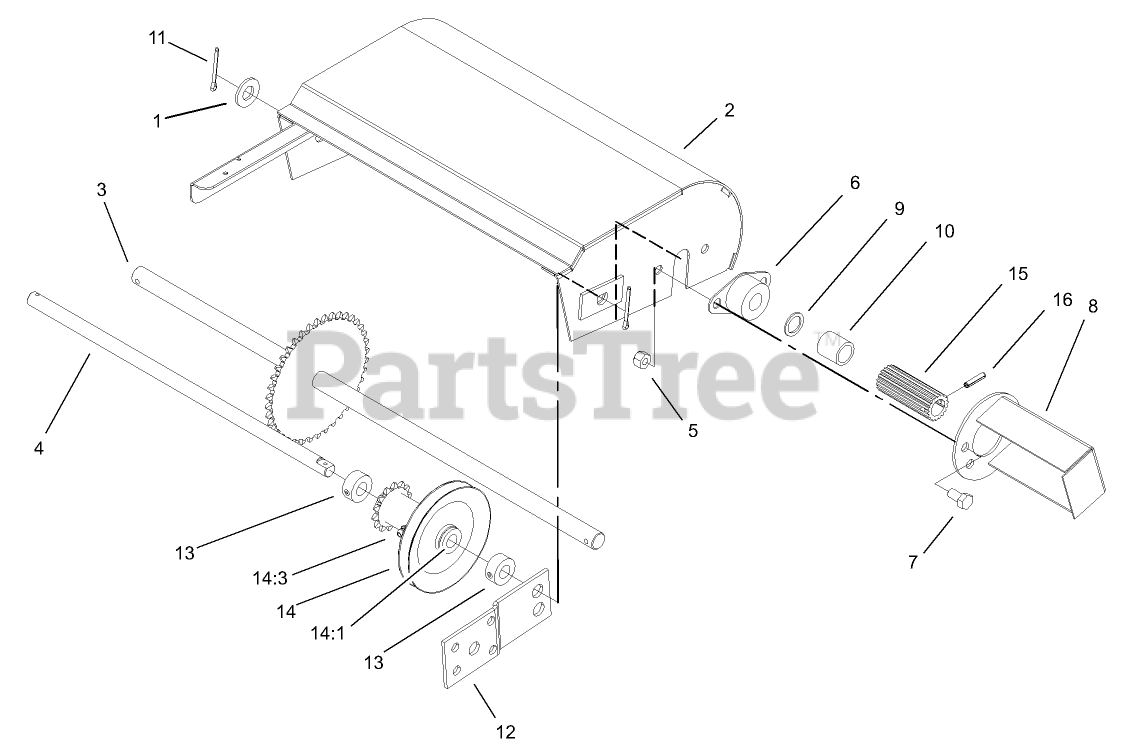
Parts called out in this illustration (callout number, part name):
1	WASHER-FLAT
3	SHAFT-WHEEL, FRICTION
4	SHAFT-IDLER
5	NUT-LOCK, NI
6	BEARING-FLANGE
7	SCREW-HH
9	WASHER
10	SPACER
11	PIN-COTTER
12	BRACKET-MOUNTING
13	COLLAR
14	IDLER ASM
14:1	BUSHING-FLANGE
14:3	FITTING-GREASE
15	WHEEL-FRICTION
16	PIN-ROLL, SLOTTED
